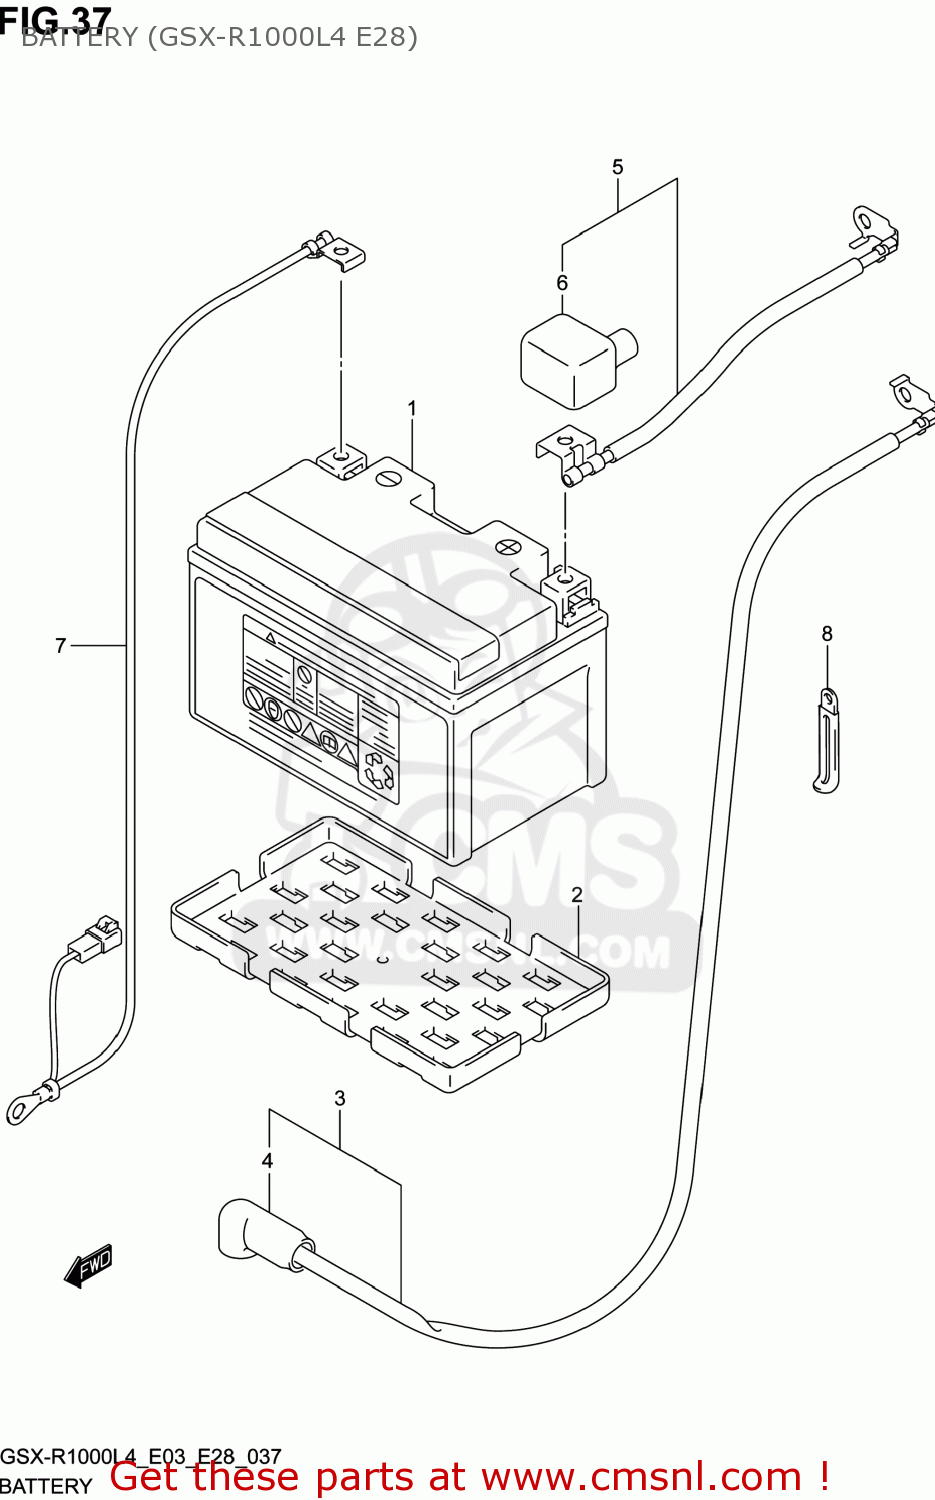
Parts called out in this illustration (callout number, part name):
1	BATTERY ASSY(FT12A-BS,12V10AH)
2	PROTECTOR,BATTERY
3	WIRE,STARTER MOTOR LEAD
4	CAP,OIL PRESSURE SWITCH
5	WIRE,BATTERY PLUS LEAD
6	CAP,BATTERY PLUS
7	WIRE,BATTERY MINUS LEAD
8	CLAMP(L:45)
